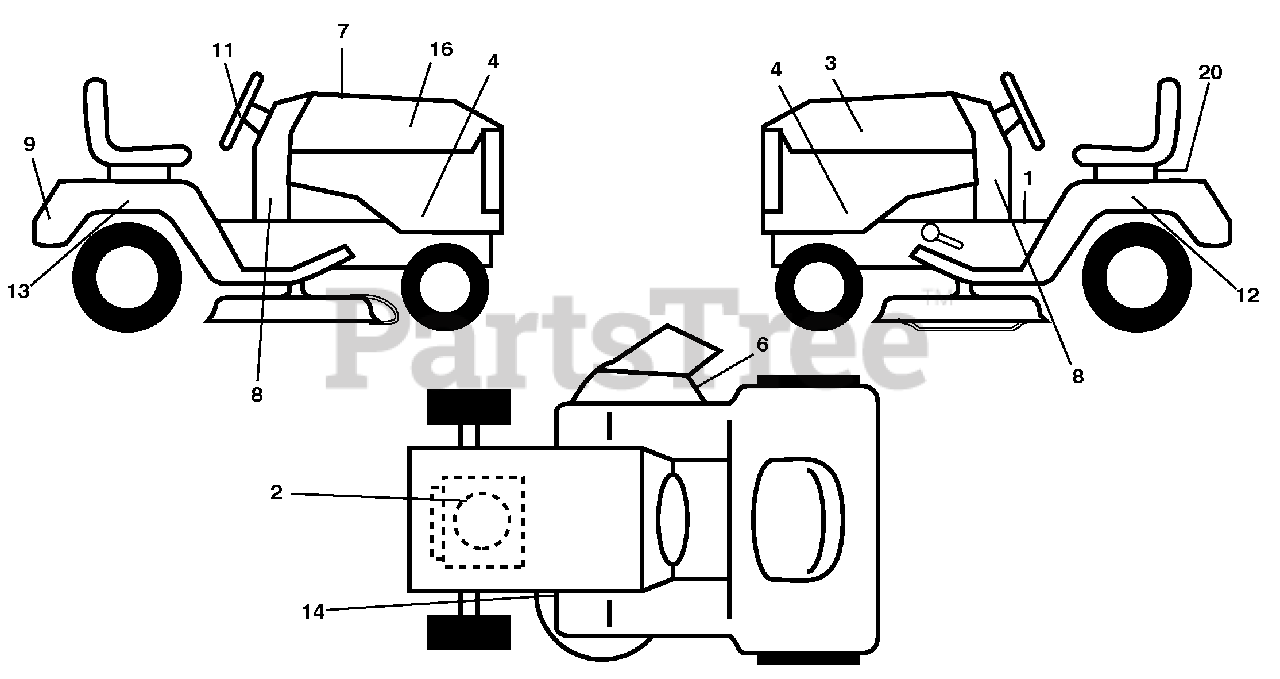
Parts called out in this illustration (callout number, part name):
1	Decal Fender Warning
2	Decal Engine H.P.
3	Decal Hood LH
4	Decal Side Panel
6	Decal Warning, Keep Hand Away
7	Decal Replacement Parts
8	Decal LWRDASH
9	Decal Fender Logo
11	Decal Ins Strg Whl
12	Decal Fender SD RH
13	Decal Fender SD LH
14	Decal V-Belt Schematic
16	Decal Hood RH
20	Decal Bat Dan/Psn
20	Pad Footrest LH
20	Pad Footrest RH
20	Decal Bypass
20	Manual Operator's English/French
20	Manual Parts
